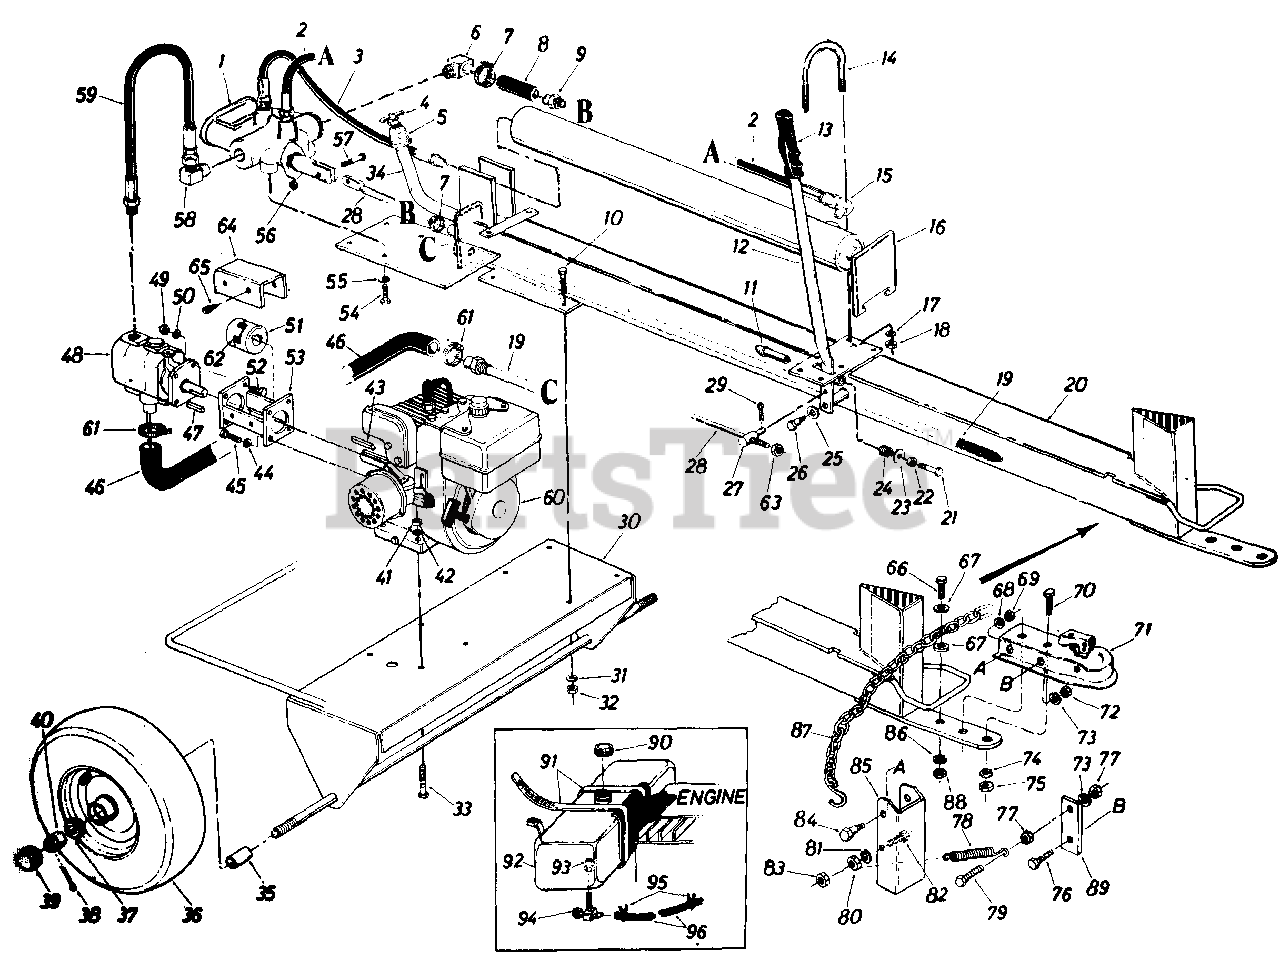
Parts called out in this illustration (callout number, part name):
1	Control Valve
2	Return Stroke High Pressure Hose
3	Forward Stroke High Pressure Hose
4	Breather Valve
5	Female Adapter 3/4-14 x 1/4-28 N.P.T.F.
6	Return Elbow
7	Hose Clamp 3/4" I.D.
8	Return Hose 3/4" I.D. x 2.62" Lg.
9	Nipple 1/2-14 N.P.T.F. x 1.5" Lg.
10	Hex Bolt 5/16-24 x 1.00" Lg. (Grade 5)
11	Return Stroke Stop Plunger
12	Engagement Handle
13	Grip
14	Cylinder Support Rod (for 3-1/2" Dia.)
15	High Pressure 90° Elbow 3/8 N.P.T. x 9/16-18
16	Cylinder Ass'y.
17	L.-Wash. 3/8" I.D.
18	Hex Nut 3/8-16 Thd.
19	Strainer Tube Ass'y.
20	Complete Oil Tank & Beam
21	Hex Bolt 5/16-24 x 1.50" Lg.
22	Hex Nut 5/16-24 Thd.
23	Fl.-Wash. .34 I.D. x .88" O.D.
24	Compression Spring .64 O.D. x .82 Lg.
25	Fl.-Wash. .53" I.D. x .94" O.D.
26	Shld. Bolt .500" Dia. x .340
27	Pivot Bushing
28	Engagement Rod .38 Dia. x 32" Lg.
29	Cotter Pin 3/32" Dia. x .75" Lg.
30	Frame Ass'y.
31	L.-Wash. 5/16" I.D.
32	Hex Nut 5/16-24 Thd.
33	Hex Bolt 5/16-24 x 1.75" Lg.
34	Filler Tube
35	Spacer .75" I.D. x 1.12" O.D. x 1.56"
37	Tapered Roller Bearing
38	Cotter Pin 5/32" Dia. x 1.00" Lg.
39	Hub Cap
40	Hex Castle Nut 3/4-16 Thd.
41	Hex Nut 5/16-24 Thd.
42	L.-Wash. 5/16" I.D.
43	Sq. Key 1/4" x 1.00" Lg.
44	L.-Wash. 5/16" I.D.
45	Hex Bolt 5/16-24 x .75" Lg.
46	Suction Hose
47	Woodruff Key
48	Pump with Woodruff Key
49	Hex Nut 5/16 24 Thd.
50	L.-Wash 5/16" I.D.
51	Flexible Coupling
52	Hex Bolt 5/16-24 x 1.00" Lg.
53	Coupling Support Brkt. Ass'y.
54	Hex Bolt 3/8 16 x .75" Lg.
55	Belleville Wash. 3/8" I.D.
56	Hex Cent. L.-Nut 1/4-20 Thd.
57	Hex Bolt 1/4-20 x 1.25" Lg.
58	90° Solid Male Adapter
59	High Pressure Hose Ass'y.
60	Engine B & S - 5 H.P.
61	Hose Clamp 1" I.D.
63	Hex Nut 3/8-24 Thd.
64	Coupling Shield
65	Hex Self Tap. Scr, 1/4-20 x .38"
66	Hex Bolt 3/8-24 x 1.75" Lg.
67	Fl.-Wash. 3/8" I.D. x 7/8" O.D. x .09
68	L.-Wash. 1/4" I.D.
69	Hex Nut 1/4-20 Thd."
70	Hex Bolt 3/8-24 x 1.25" Lg.
71	Tow Hitch Ass'y. Comp.
72	Hex Nut 5/16-18 Thd.
73	L.-Wash. 5/16" I.D.
74	L.-Wash. 3/8" I.D.
75	Hex Nut 3/8-24 Thd.
76	Hex Bolt 5/16-18 x .75" Lg.
77	Hex Nut 5/16-18 Thd.
78	Extension Spring
79	Hex Bolt 5/16-18 x 1.50" Lg.
80	Hex Nut 1/4-28 Thd.
81	L.-Wash. 1/4" I.D.
82	Hex Bolt 1/4-28 x 1.00" Lg.
83	Hex L. Nut 1/4-28 Thd.
84	Shld. Bolt .374" Dia. x .171" Lg.
85	Flip Stand Bracket
86	L.-Wash. 3/8" I.D.
87	Chain 40" Lg. Tow Hitch
88	Hex Nut 3/8-24 Thd.
89	Spring Mtg. Bracket
90	Gas Tank Cap
91	Gas Tank Straps
92	Gas Tank
93	Gas Tank Bushing
94	Shut Off Valve
95	Gas Line Clamp
96	Gas Line - 15" Lg.
